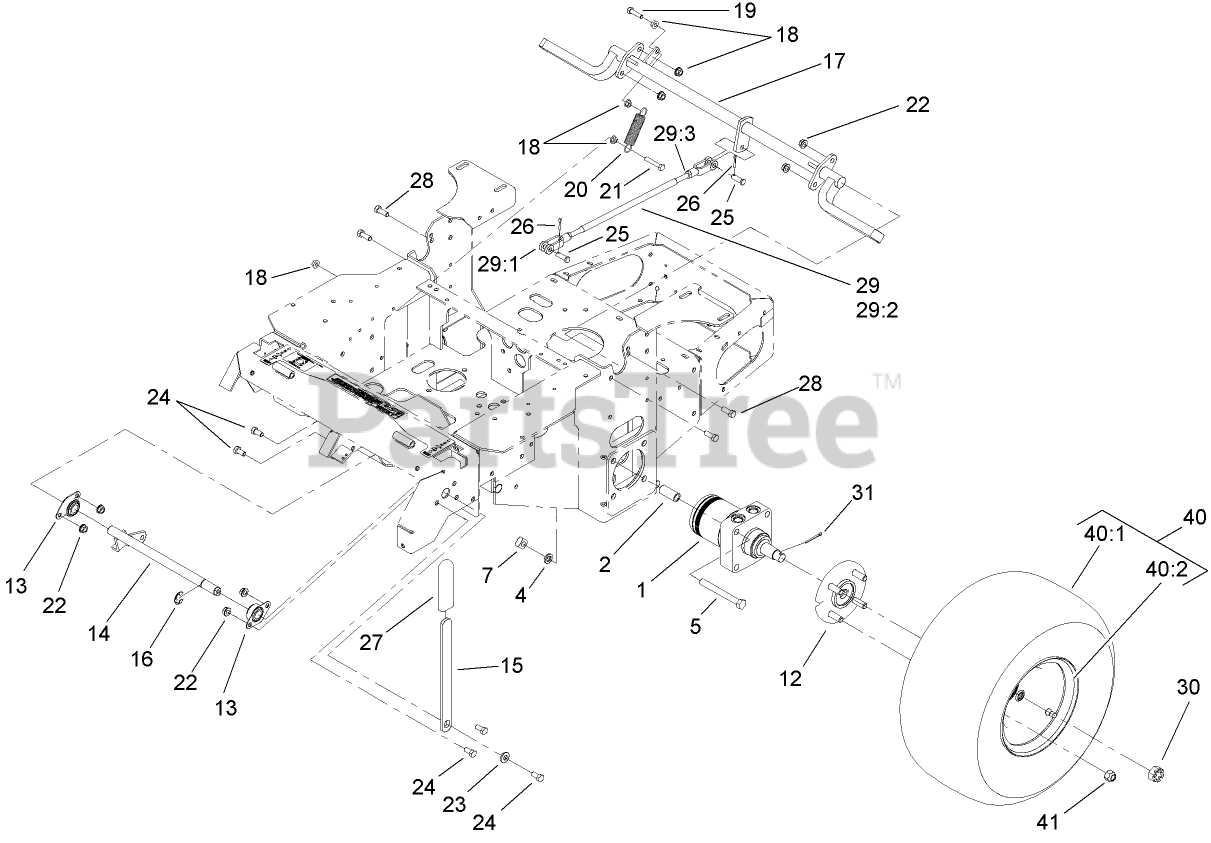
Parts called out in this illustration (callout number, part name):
1	MOTOR-WHEEL
2	SPACER-MOTOR, WHEEL
4	WASHER-LOCK
5	SCREW-HH
7	NUT-SQUARE
12	WHEEL HUB ASM
13	BEARING-FLANGE, SIDE
14	Shaft-Brake, Parking
15	HANDLE-BRAKE, PARKING
16	E-RING
18	NUT-HF
19	SCREW-HH
20	SPRING-IDLER
21	SCREW-HH
22	NUT-HHF, WHIZ
23	WASHER-BELLEVILLE
24	SCREW-HH
25	PIN-CLEVIS
26	PIN-COTTER
27	GRIP-LEVER
28	SCREW-HH
29	BRAKE ROD ASM
29:1	YOKE-LINKAGE, BRAKE
29:2	LINKAGE-HANDLE, BRAKE
29:3	NUT-HEX
30	NUT-HEX, SLOTTED
31	PIN-COTTER
40	WHEEL AND TIRE ASM
40:1	TIRE
41	NUT-LUG
